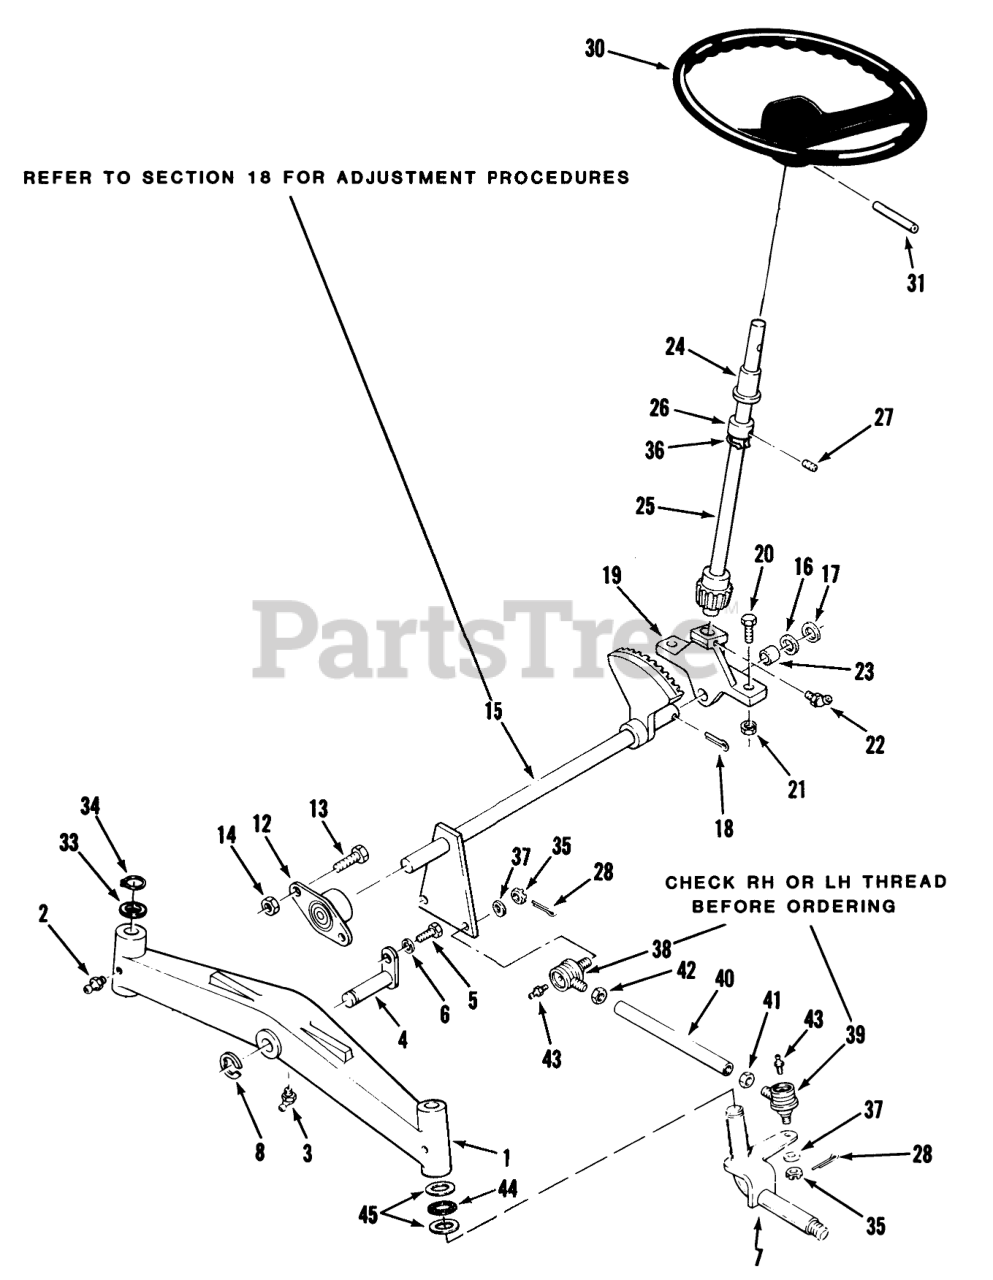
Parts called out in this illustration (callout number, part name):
1	Axle-Front
2	Zerk
3	FITTING-GREASE
4	PIN AND PLATE ASM
5	H H C S
6	Lockwasher
7	Spindle
8	E-RING
12	BEARING-FLANGED
13	Bolt
14	NUT
15	ASS'Y-STRG SHAFT R
16	WASHER-SHIM
17	WASHER
18	PIN-4
19	Support
20	Bolt
21	NUT
22	FITTING-GREASE
23	BEARING-BRONZE
24	BEARING-FLANGED
25	WLDMT-UPPER SHAFT R
26	COLLAR
27	SCREW-SET
28	TUBE-STEERING
30	Steering Wheel
31	Pin-Roll
33	WASHER
34	Snap Ring
36	RING-RETAINING
37	WASHER
38	SOCKET-BALLJOINT
39	SOCKET-BALLJOINT
40	Tube
41	NUT-HEX JAM 9/16-18
42	Nut
43	Grease Fitting
44	BEARING-THRUST
45	WASHER-THRUST
